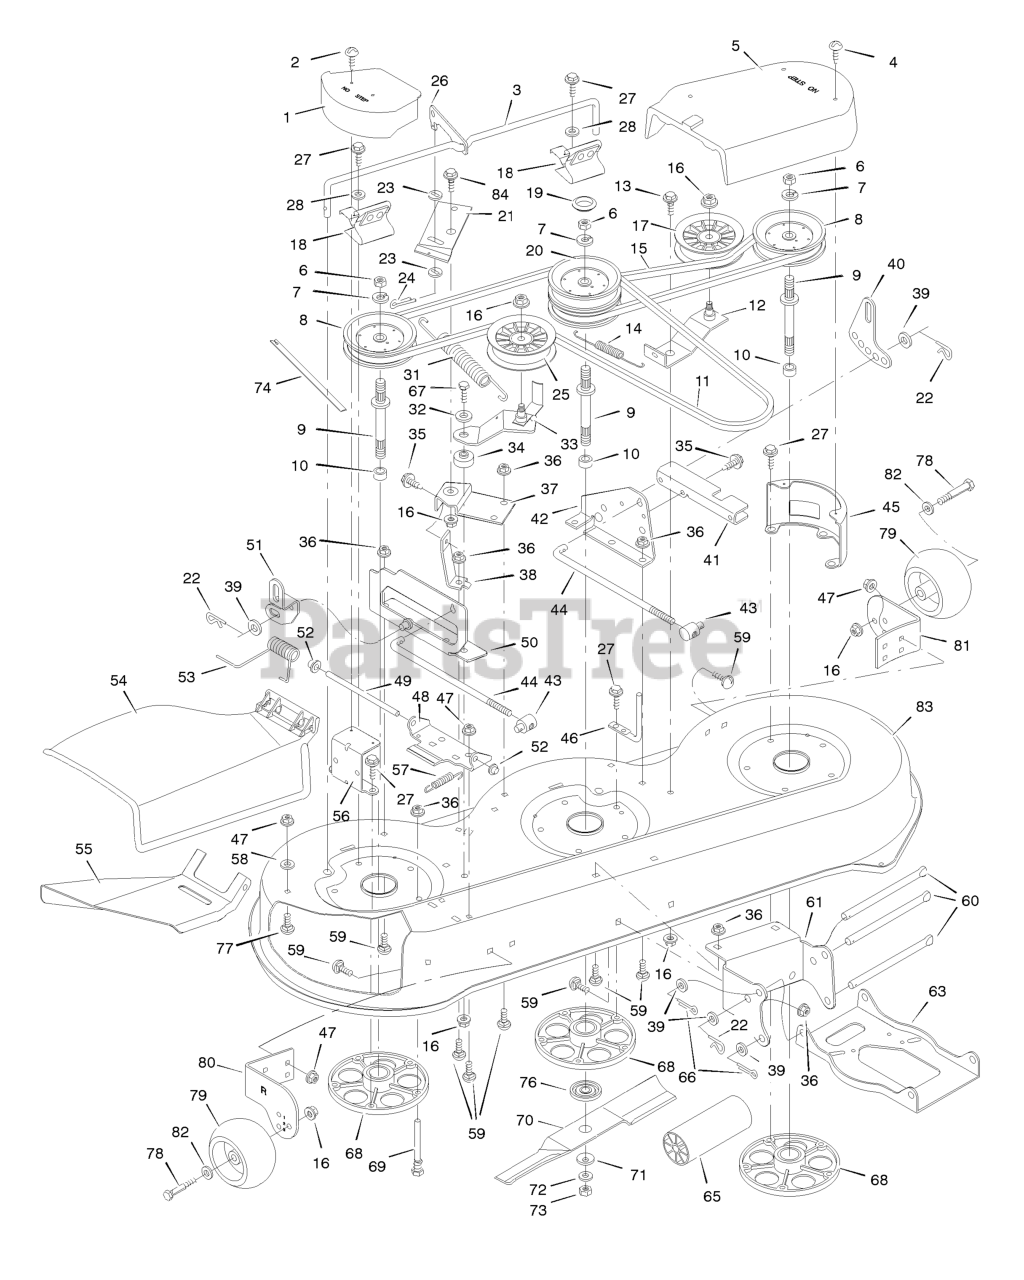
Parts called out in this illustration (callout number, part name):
1	Cover, Pulley
3	Rod, Brake
5	Cover, Left Pulley
6	Nut, Hex
7	Lockwasher
9	Jackshaft
10	Spacer, Bearing
11	Belt, Primary Mower Drive
12	Bracket, Idler
13	Bolt, Shoulder
14	Spring, Extension
15	Belt, Secondary Mower Drive
16	Locknut
17	Pulley, Idler
18	Spring Assembly, Brake
20	Pulley, Stack
21	Bracket, Pivot
22	Pin, Hair
24	Pin, Cotter
25	Pulley, Idler
26	Link, Brake
27	Screw
31	Spring, Extension
33	Bracket, Idler
34	Bushing
36	Nut, Hex
37	Support, Pivot
38	Strut, Pivot
40	Plate, Adjuster
41	Channel, Left Cover
42	Bracket Assembly, Lifter
43	NUT, Adjusting, 1/2-13
44	Rod, Adjuster
45	Bracket, Left Cover
46	Guide, Belt
47	Locknut
48	Bracket, Hinge
49	Rod, Deflector
50	Bracket Assembly, Lifter
51	Link, Suspension
52	Push- On Cap
53	Spring, Torsion
54	Deflector
55	Deflector, Inside
56	Bracket, Cover
57	Spring, Extension
59	Bolt, Carriage
60	Rod, Hanger
61	Bracket, Front Hanger
63	Hanger, Front
66	Pin, Cotter
67	Bolt, Hex
68	Housing, Mandrel
69	Guide, Belt
70	Blade (3 required)
71	Washer, Belleville
73	Nut, Hex
74	Indicator, Plastic
76	Adapter, Blade
77	Bolt, Carriage
78	BOLT, Gauge Wheel
79	Wheel, Gauge
80	Bracket, Right Gauge Wheel
81	Bracket, Left Gauge Wheel
82	Washer
83	Housing, Mower
84	Bolt, Shoulder
